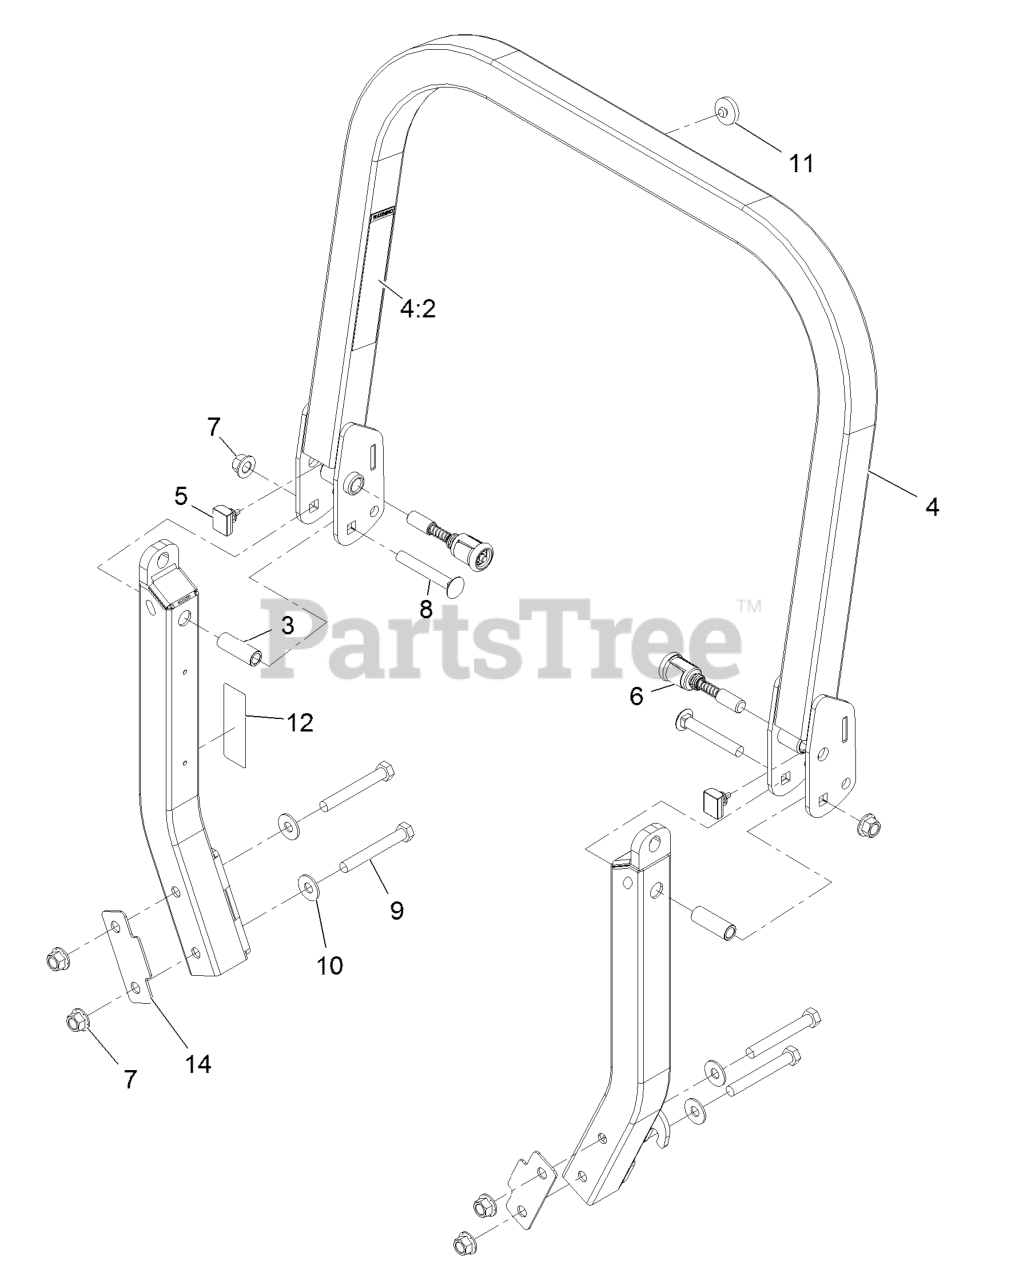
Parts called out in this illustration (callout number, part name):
4	UPPER ROPS ASM
4:2	DECAL-WARNING, FOLDING RO
5	BUMPER-ROPS
6	PIN-SPRING
7	Nut-Lock 1/2-13
8	SCREW-CARR
9	WASHER-LOCK
10	WASHER-SPRING
11	BUMPER-PUSH-IN, RUBBER
12	DECAL-CAUTION
